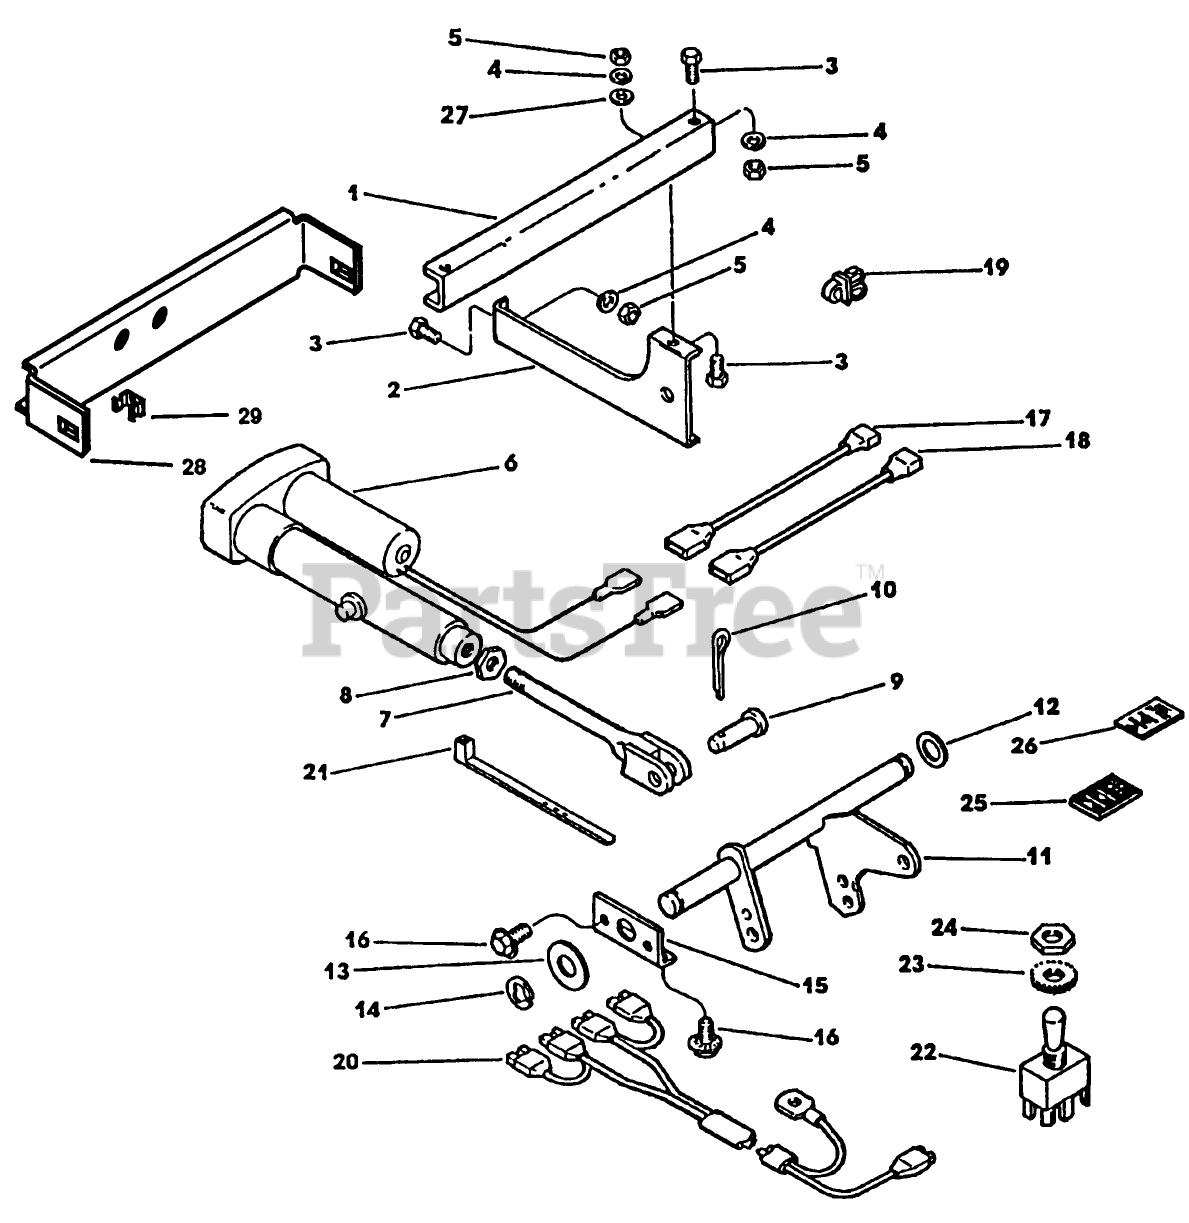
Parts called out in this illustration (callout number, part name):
3	SCREW - HEX
11	LIFT LEVER ASM
16	SCREW-HWH
23	NIT KNURLED
